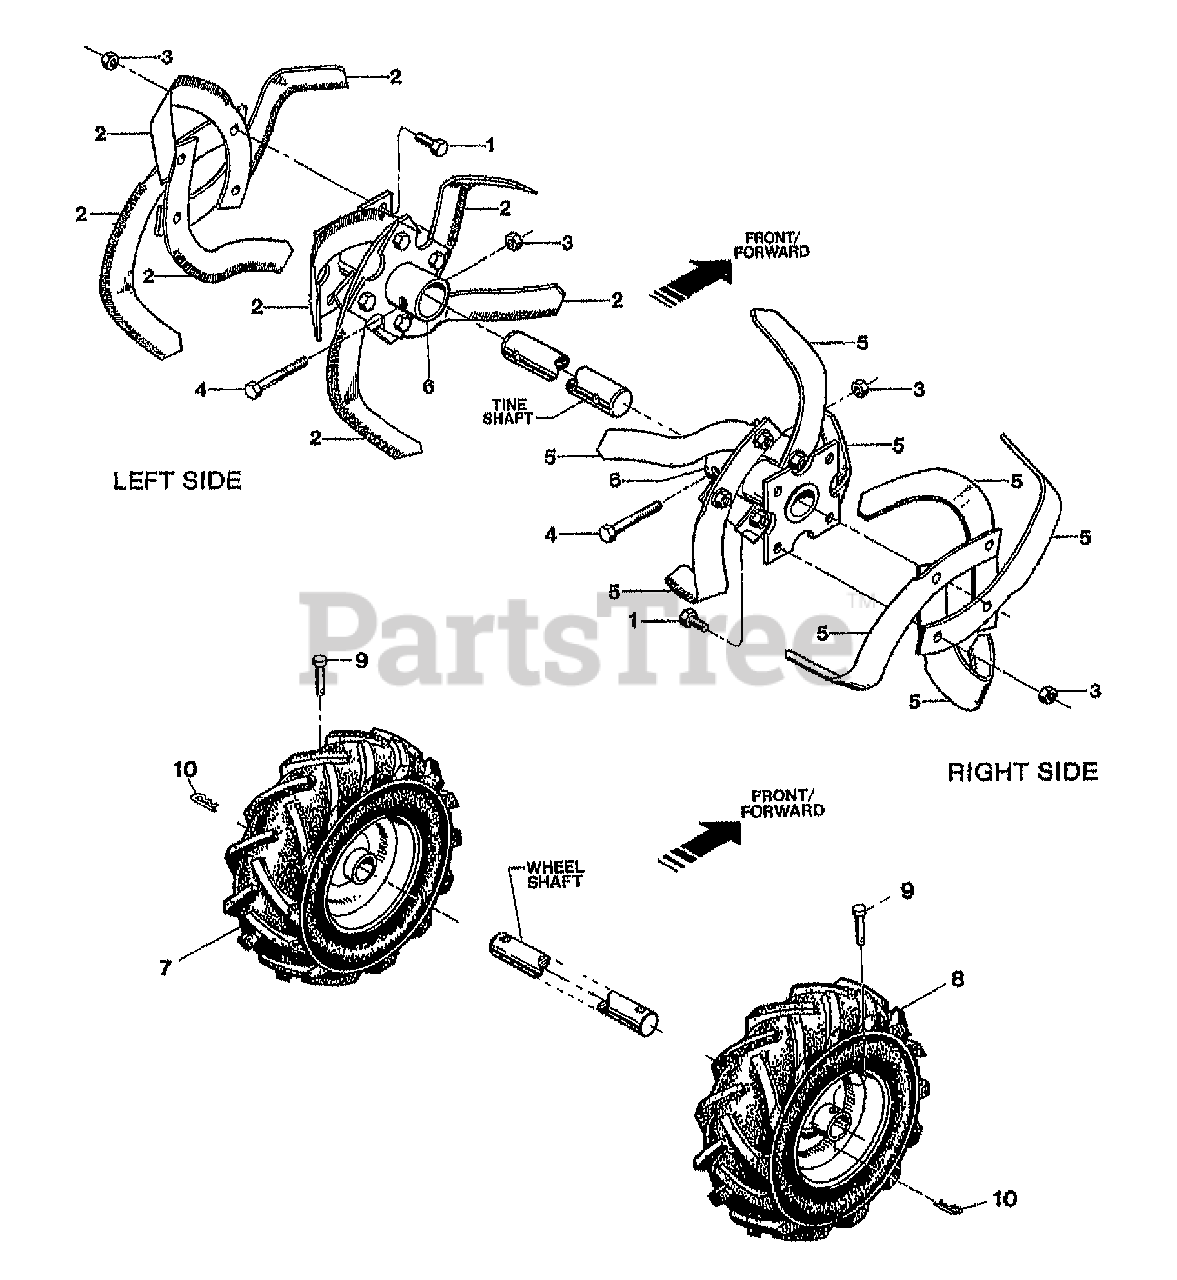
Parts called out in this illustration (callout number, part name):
1	SCR-HH 3/8-16X1.0 G5 ZP
2	TINE-BOLO RIGHT
3	NUT-LOCK 3/8-16
4	SCR-HH 3/8-16X2.00 G8 (TINE HOLDER TO TILLER SHAFT)
5	TINE-BOLO LEFT
6	HOLDER-TINE JUNIOR
6	HOLDER-TINE T/B TUFFY {12155}
7	ASSM-TIRE&WHL LH GRAY
8	ASSM-TIRE&WHL RH GRAY
9	PIN-CLEVIS
10	PIN-CLIP .08
